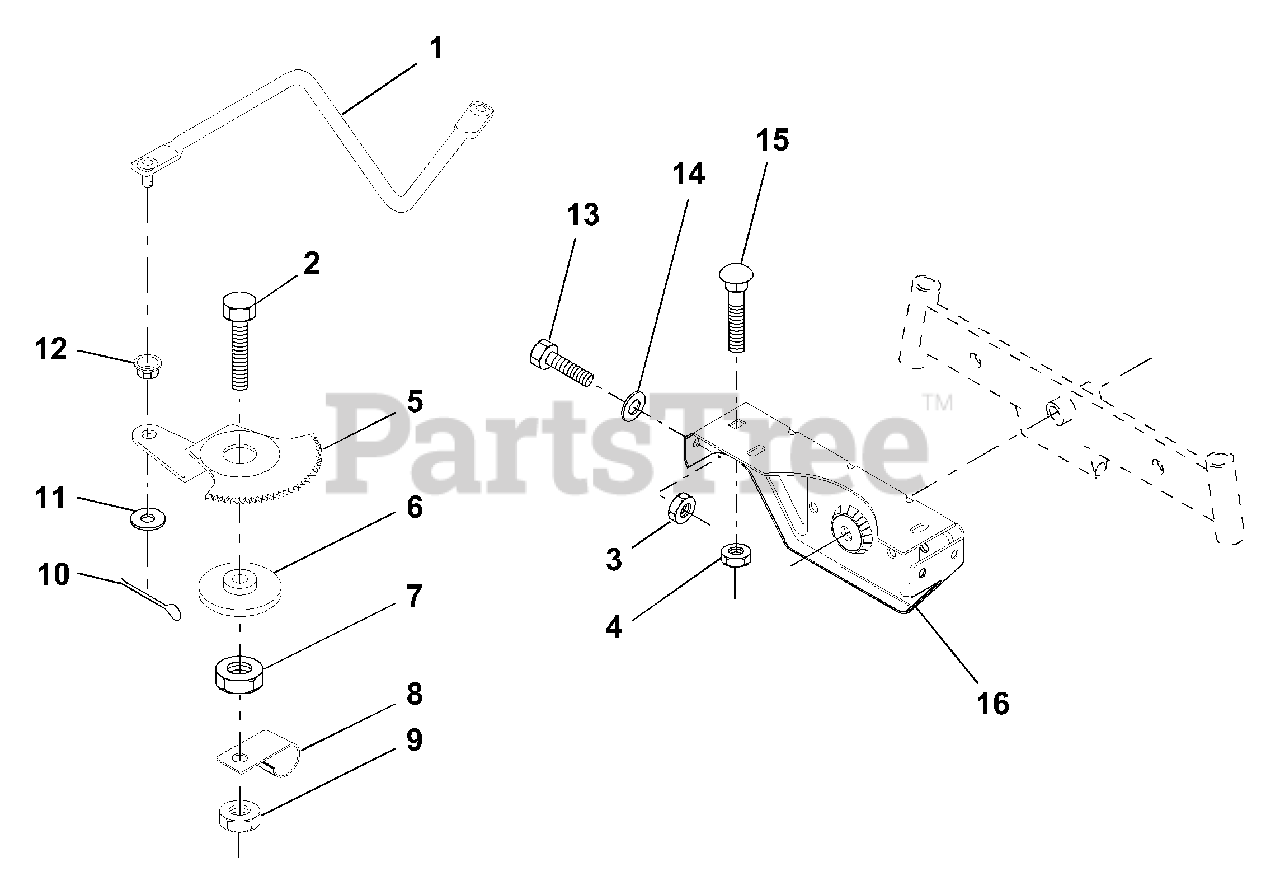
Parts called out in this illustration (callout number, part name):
1	Link, Drag
2	Bolt, Fin Hex 1/2-13 x 1-3/4
3	Nut, Crownlock 5/16-18
4	Nut, Crownlock 3/8-16 UNC
5	Gear, Sector
7	Nut, Heavy Hex Top Lock 1/2-13 UNC
8	Clip, Insulated
9	Nut, Crownlock 3/8-16
10	Pin, Cotter 1/8 x 3/4
11	Washer, 13/32 x 13/16 x 16 Ga.
13	Bolt, Hex Hd. 5/16-18 UNC x 3/4
14	Washer 11/32 x 7/8 x 16 Ga.
15	Bolt, Carriage 3/8-16 UNC x 3/4
16	Support, Front Axle
